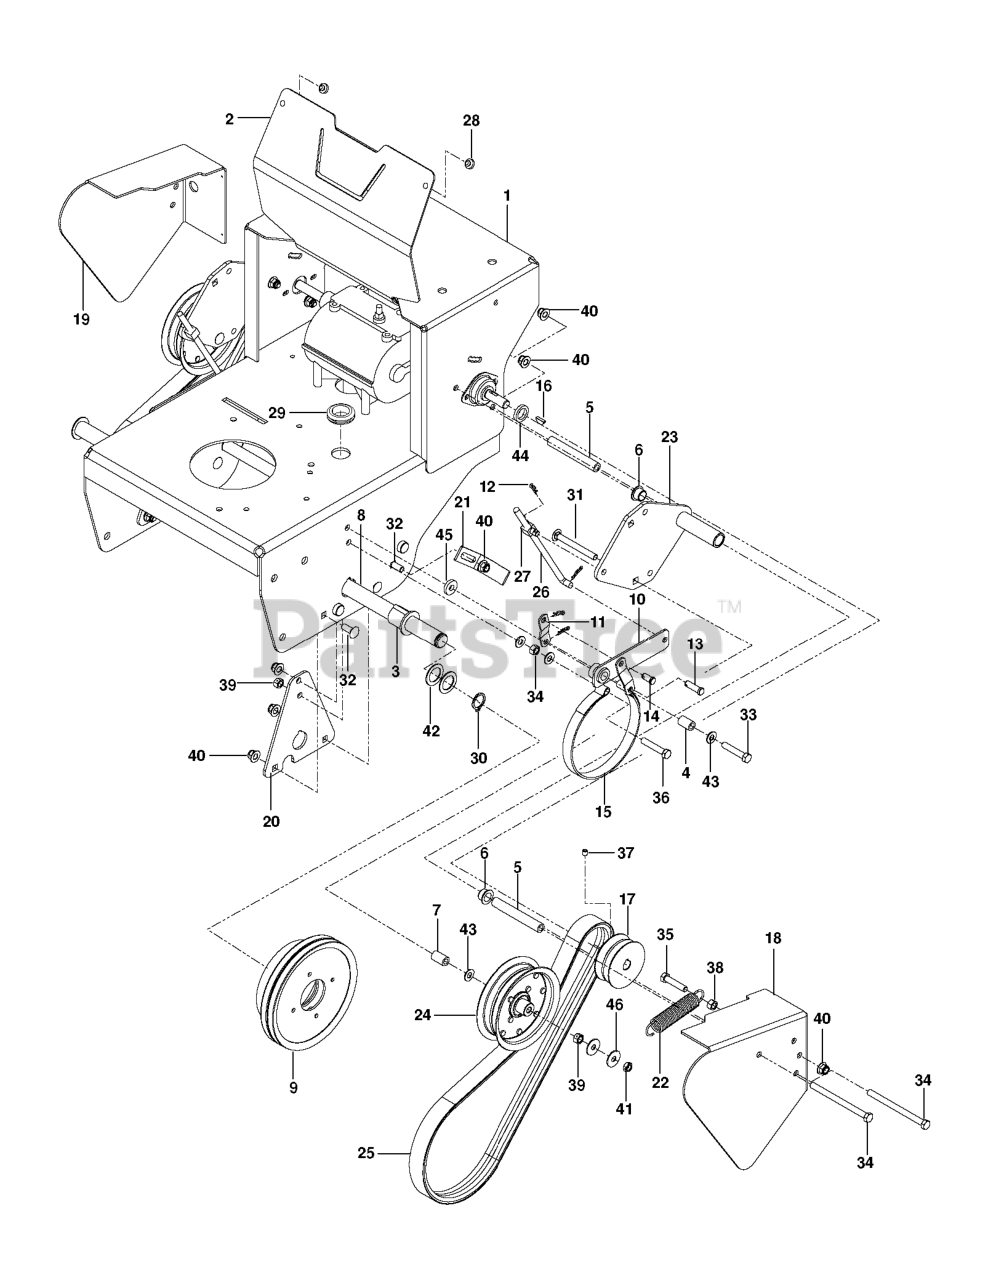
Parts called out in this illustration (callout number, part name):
1	FRAME ASSY, FRAME GRWLK W/DECA
2	SHIELD SHIELD, FUEL TANK HUSQ
3	BUSHING BUSHING FLG 1.010 X 1.
4	BUSH BUSH SLV .391 X .622 X .9
5	BUSH BUSH.,S.385 X .610 X 4.32
6	BUSHING BUSHING FLG, .625 X .7
7	BUSHING BUSHING SLV .375 X .62
8	SHAFT SHAFT, AXLE
9	PULLEY ASSY ASSY, PULLEY & DRU
10	LEVER BRAKE ACTUATING LEVER
11	LINK LINK, BRAKE ARM HUSQ
12	PIN PIN-HAIR, ENDRIES #25 YWZC
13	PIN PIN, CLEVIS .38 X 1.25 YWZ
14	PIN PIN, CLEVIS .38 X .75 YWZC
15	BRAKE BAND ASSY ASSY, BRAKE BA
16	KEY KEY-WDRF .19 X .75 HRD#9
17	SHEAVE SHEAVE,DRIVE 3.25 OD X
18	COVER COVER, LH TRACTION BELT
19	COVER COVER, RH TRACTION BELT
20	PLATE PLATE, AXLE/BRG MTG
21	PLATE PLATE, BENT BELT FINGER
22	SPRING SG-TENS .105 X 1.00 X 5
23	ARM CLUTCHING ARM HUSQ
24	PULLEY PULLEY, FLAT 5.00 X .37
25	BELT BELT, GEAR DRIVE 49" EL C
26	ROD ROD, BRAKE ACTUATING
27	SWIVEL SWIVEL, 3/8-24
28	BUMPER BUMPER GROMMET .125 X .
29	GROMMET GROMMET, RUB:.88ID X 1
30	RING RG-RTNG-E X T 1.00 X .078
31	BOLT RDHDSQNK .38-16 X 3.
32	BOLT BOLT RDHDSQNK .38-16 X 1.
33	BOLT BOLT HEX .38-16 X 2.00 GR
34	BOLT BOLT HEX .38-16 X 5.00 GR
35	BOLT BOLT HEX .38-16 X 1.75 GR
36	BOLT BOLT HEX .38-16 X 2.00 IN
37	SCREW SCREW, SET .31-18 X .38
38	NUT NUT, HEX .38-16 YWZC
39	NUT NUT, LK-CTR .38-16 YWZC
41	NUT NUT, LK-CTR-JAM .375-16 YW
42	WASHER WASHER, FL-STL 1.010 X
44	WASHER WASHER, FLT .765" X .1.
45	WASHER WASHER, FL-STL .406 X 1
46	WASHER WASHER, FL-STL .375 X 1
